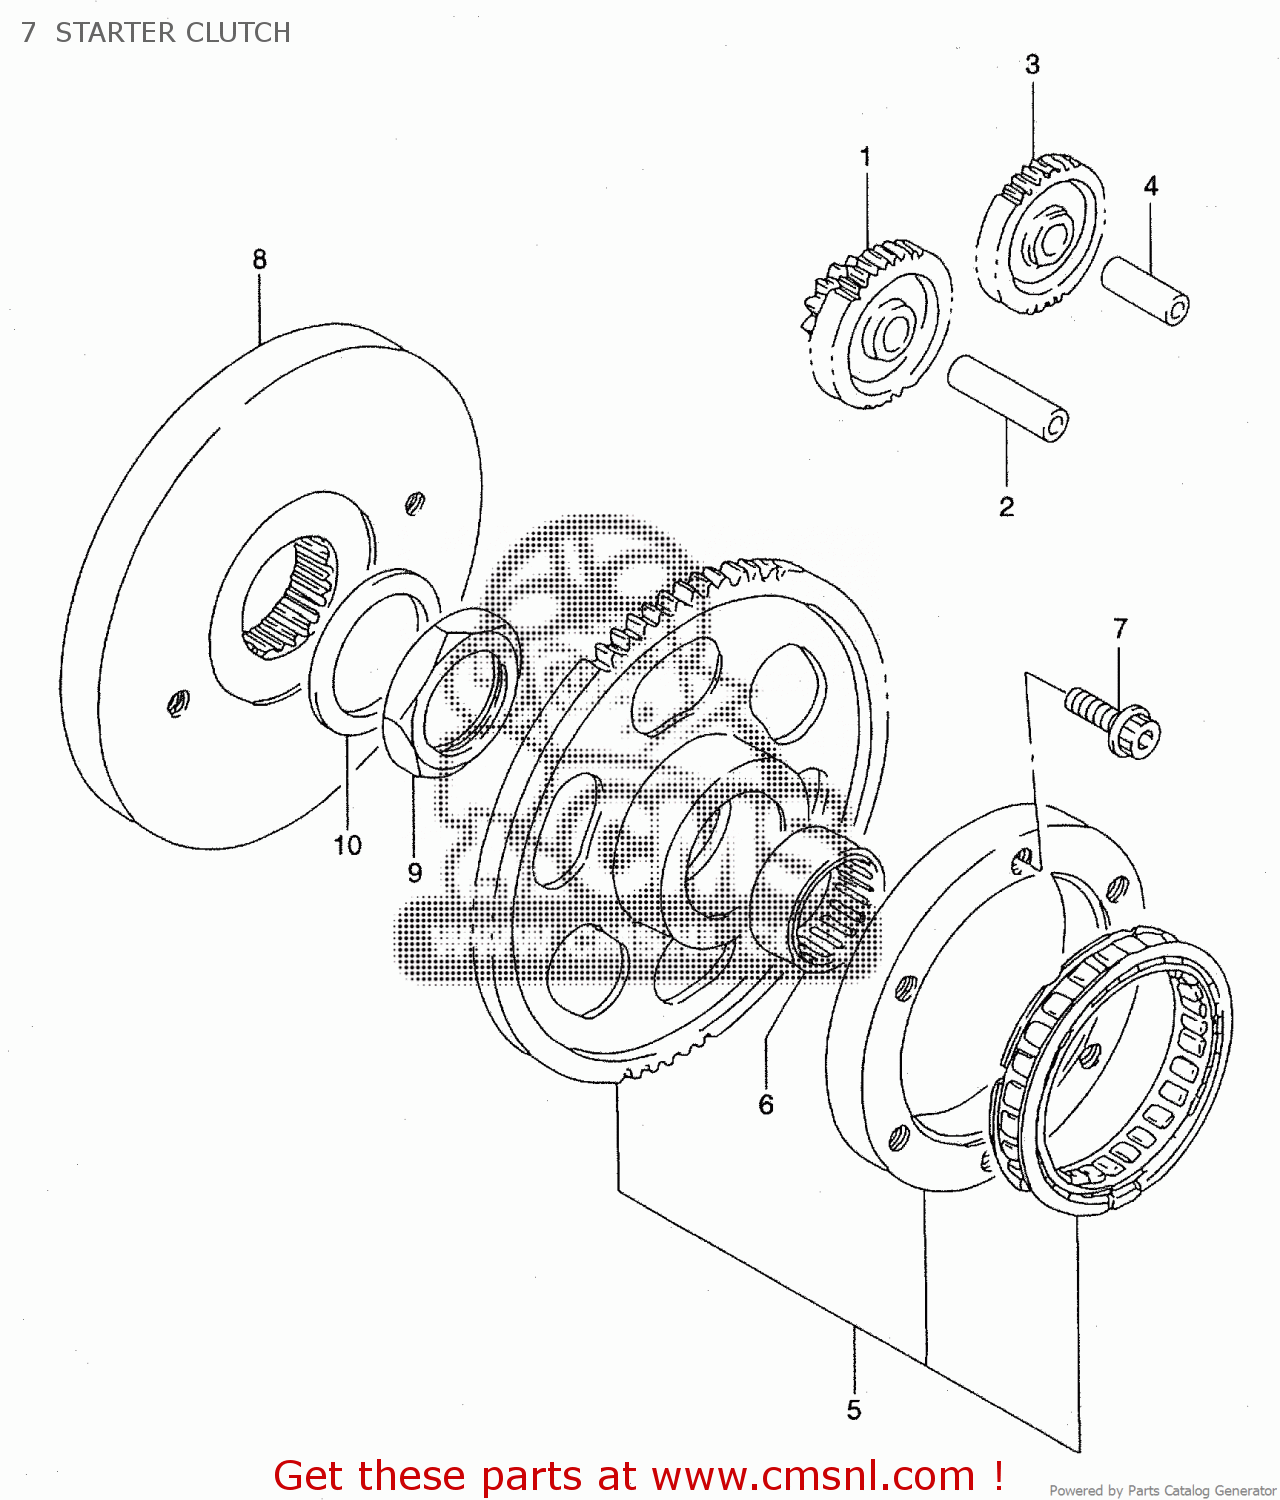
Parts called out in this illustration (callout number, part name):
1	GEAR,STARTER IDLE NO.1
2	PIN,10X43
3	GEAR,STARTER IDLE NO.2
4	PIN(10X30)
5	CLUTCH SET,STARTER
6	BEARING(31X39X17.8)
7	BOLT
8	FLYWHEEL
9	NUT,FLYWHEEL
10	WASHER
